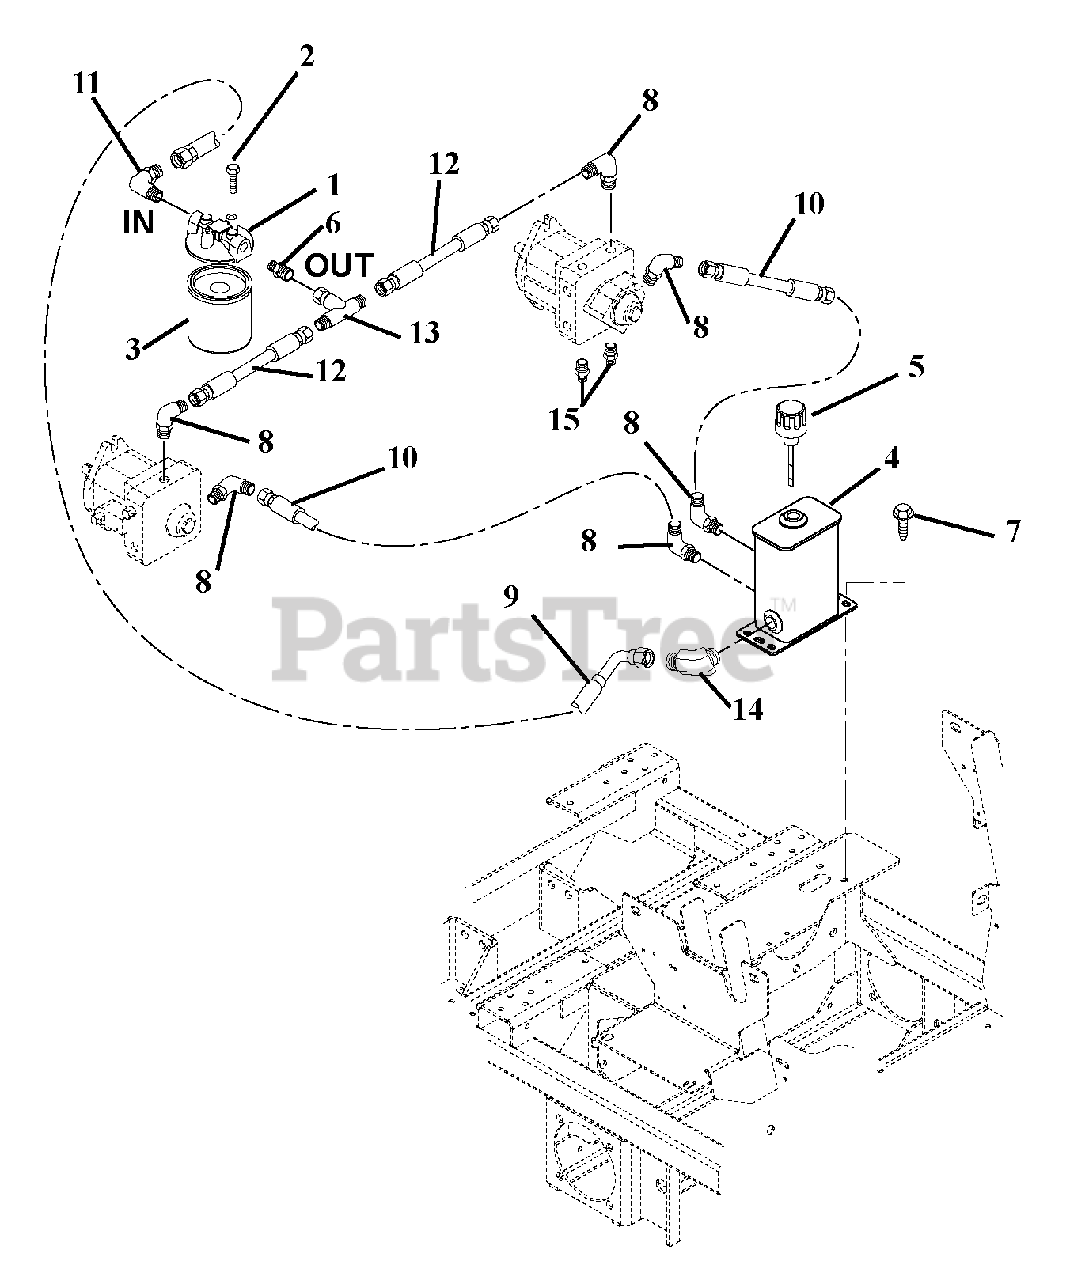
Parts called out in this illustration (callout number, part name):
1	Filter Housing
2	Bolt-Hex .25-20 x .50 Grade 5 Epoxy
3	Filter Element
4	Body, Hydraulic Tank
5	Breather, Dipstick
6	Fitting, Hydraulic, Straight Steel
7	Screw-Tapping .38-16 x .75 Hex Washer Head
8	Fitting, Hydraulic, 90 Degree Elbow
9	Hose-Hydraulic Valve to Tank
10	Hose, Hydraulic, 10-inch
11	Fitting, Hydraulic, 90 Degree Elbow
12	Hose, Hydraulic .50, 5-Inch
13	Fitting, Hydraulic Tee
14	Fitting, Hydraulic .45 Degree Elbow
15	Fitting, Hydraulic (4 F5OLO)
